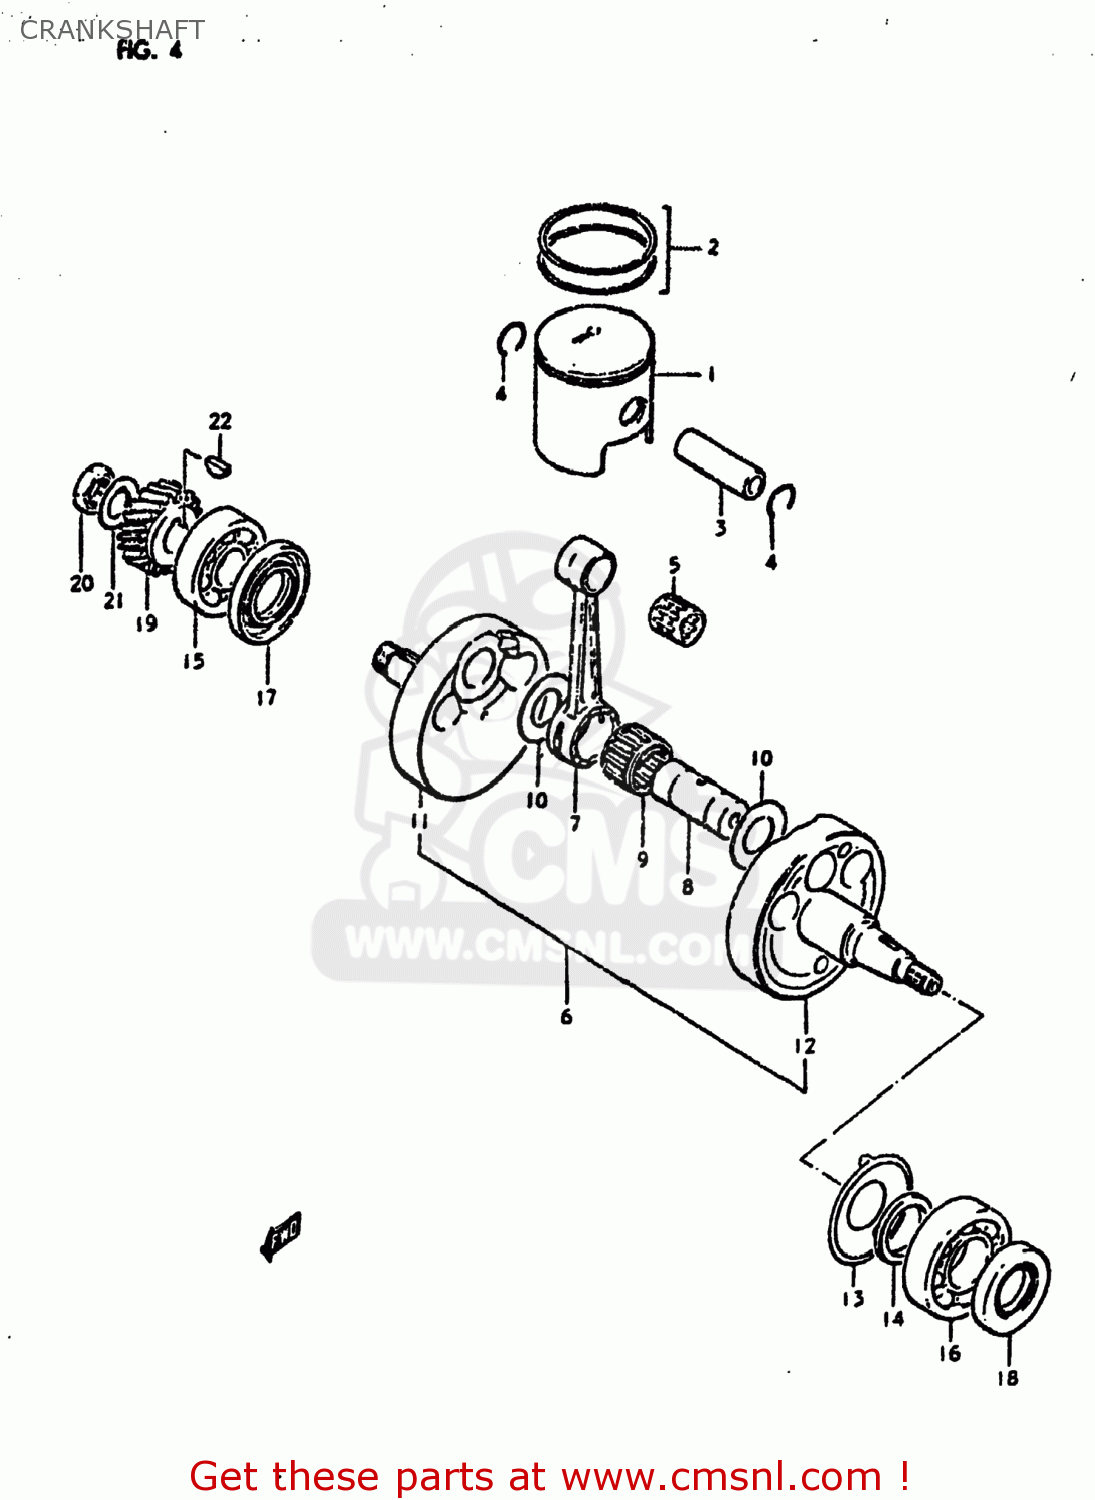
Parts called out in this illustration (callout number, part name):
1	PISTON
2	RING SET,PISTON
3	PIN,PISTON (18MM)
4	CIRCLIP
5	BEARING
6	CRANKSHAFT ASSEMBLY
7	ROD,CONNECTING
8	PIN,CRANK
9	BEARING(25X31X20)
10	WASHER(25X40X1)
11	CRANKSHAFT,RIGHT
12	CRANKSHAFT,LEFT
13	PLATE,CRANKSHAFT OIL GUIDE
14	SPACER (30X45X4.8)
15	BEARING
16	BEARING(30X72X19)
17	SEAL,OIL(35X62X9)
18	OIL SEAL
19	GEAR,PRIMARY DRIVE
20	NUT
21	WASHER
22	KEY
